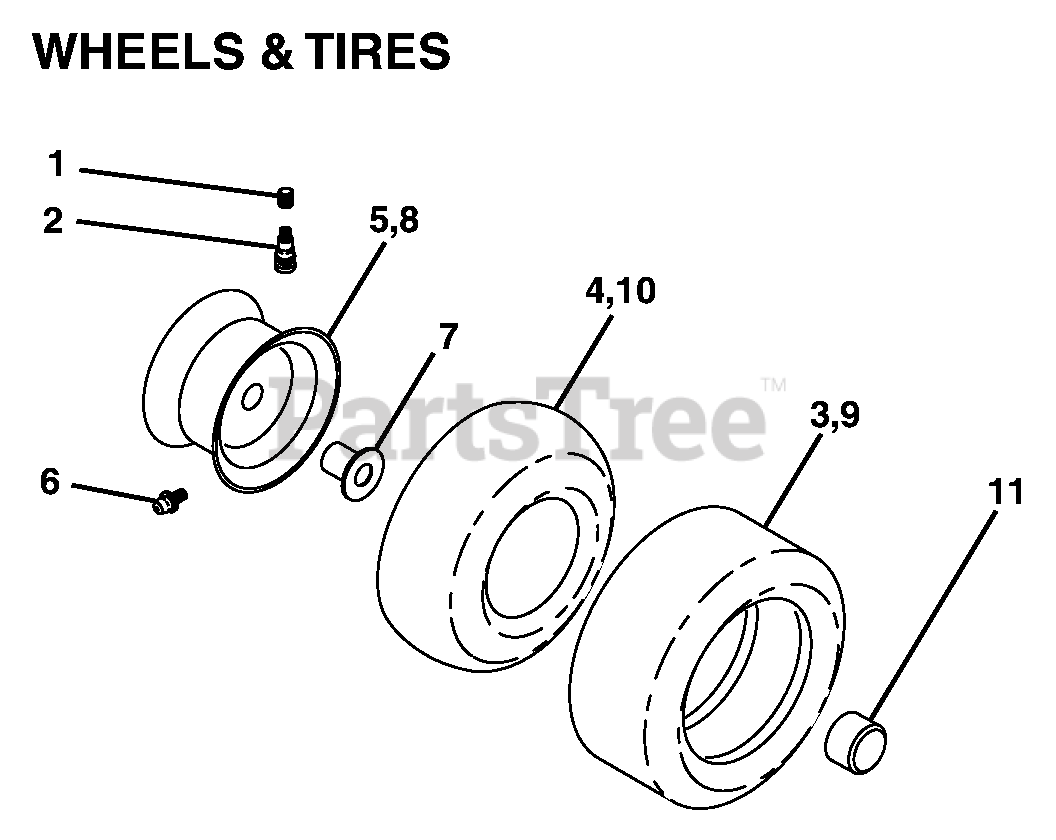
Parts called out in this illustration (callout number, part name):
1	Cap Valve Tire
2	Stem Valve
3	Tire F T 15 x 6 0 - 6 Service
4	Tube Front (Service Item Only)
5	Rim Asm 6"front Service
6	Fitting Grease (Front Wheel Only)
7	Bearing Flange (Front Wheel Only)
8	Rim Asm 8"rear Service
9	Tire R T 20 x 8-8 C Service
10	Tube Rear (Service Item Only)
11	Cap Axle 1 50 x 1 00
